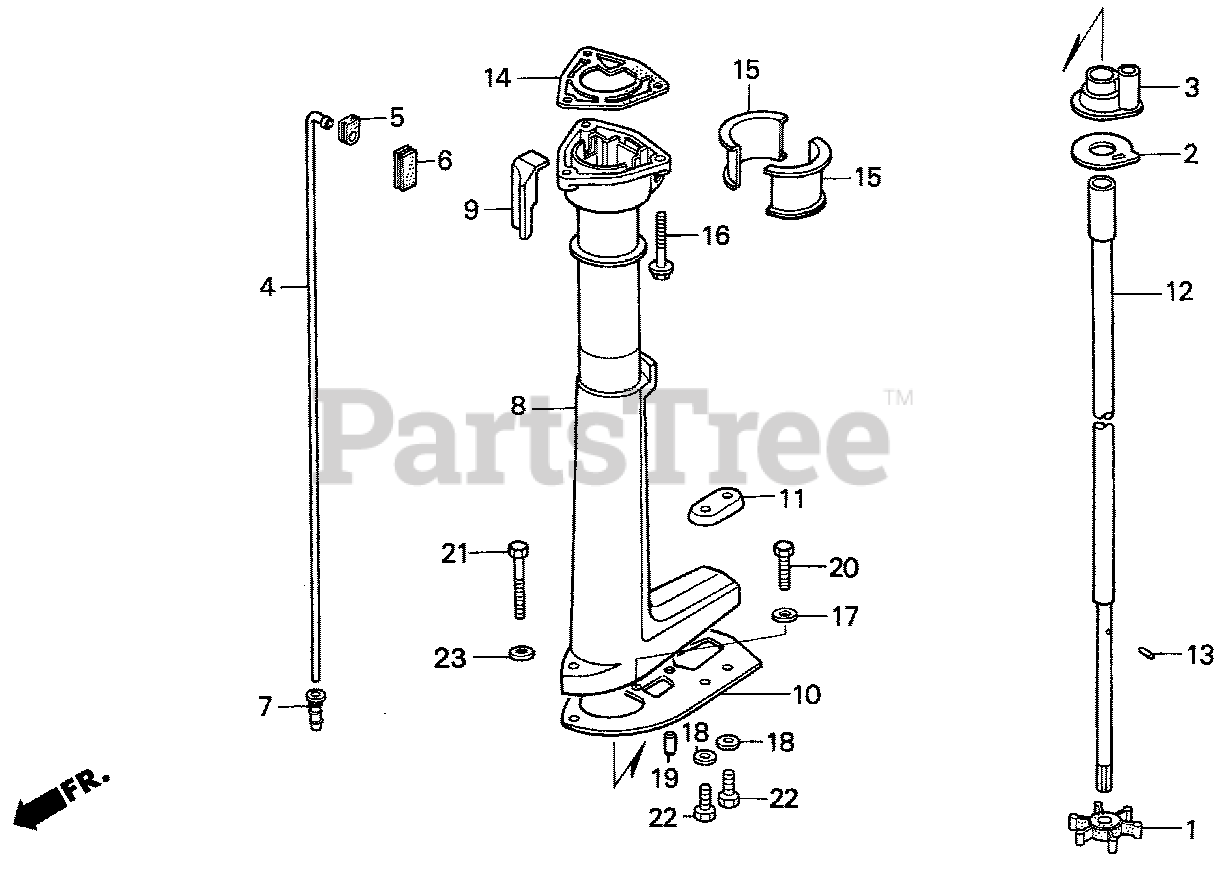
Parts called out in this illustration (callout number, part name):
1	IMPELLER, WATER PUMP
2	COVER, IMPELLER
3	HOLDER, IMPELLER COVER
4	TUBE, L. WATER
5	RUBBER A, WATER SEAL
6	RUBBER B, WATER SEAL
7	GROMMET, WATER PUMP
8	CASE, EXTENSION *NH210MC* (AQUA SILVER METALLIC-C)
9	GUIDE, EX.
12	SHAFT, L. VERTICAL
13	PIN, VERTICAL SHAFT
14	GASKET, CASE (UPPER)
15	LINER, SWIVEL CASE
16	BOLT, FLANGE (6X32)
21	BOLT, HEX. (6X35)
